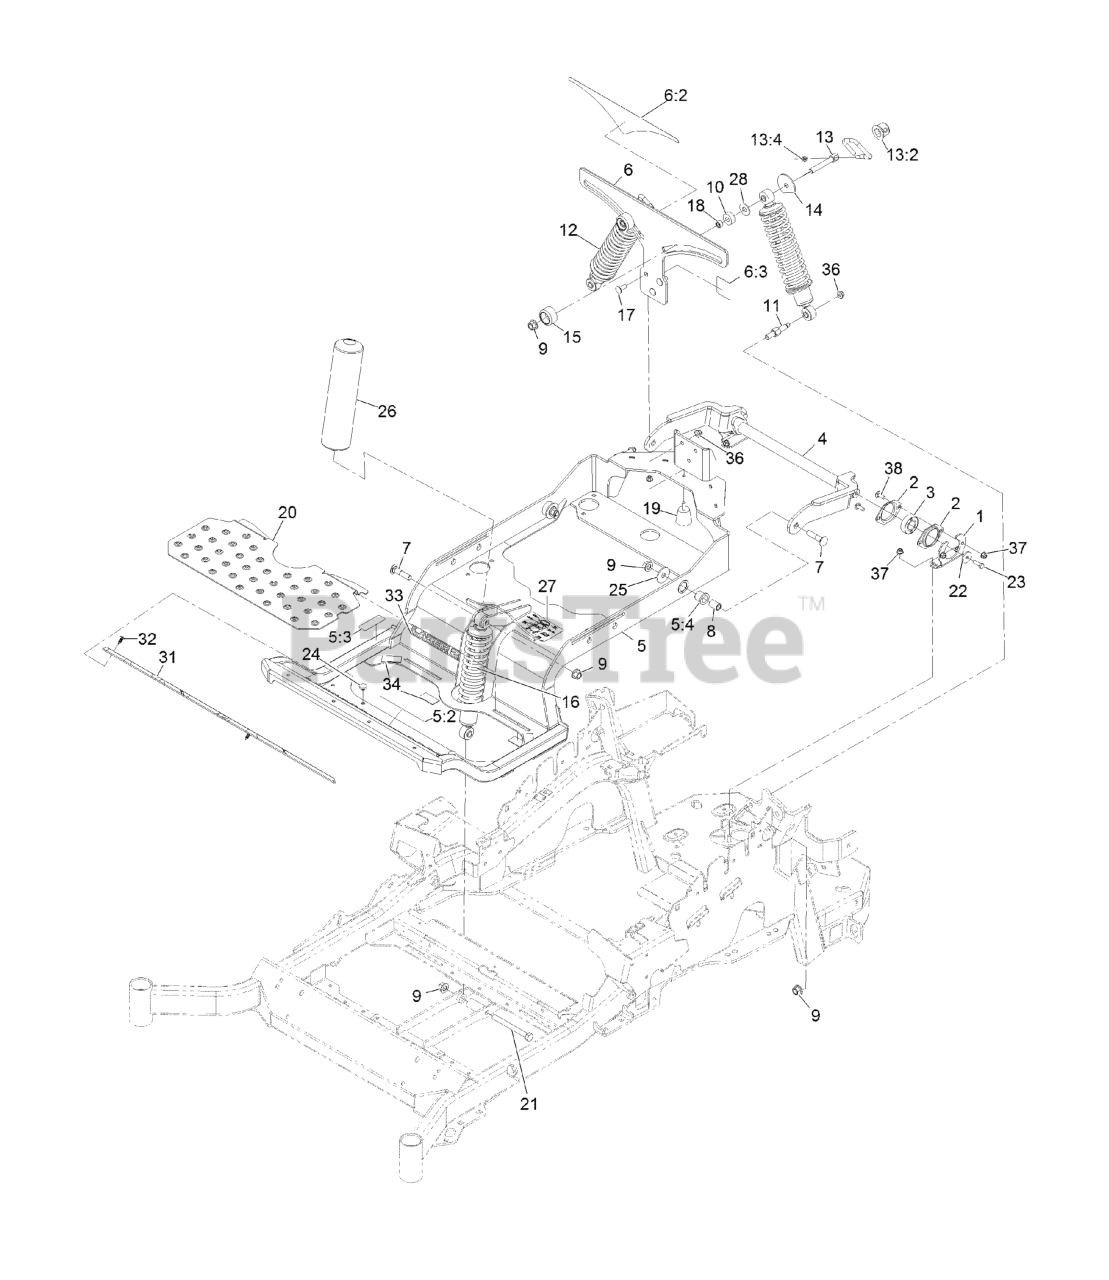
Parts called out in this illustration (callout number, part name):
1	BRACKET-BEARING
2	HOUSING-BEARING, FLANGE
3	BEARING
4	ARM-TRAILING
5	SUBFRAME ASM
5:2	DECAL-DANGER
5:3	DECAL-BRAKE, PARKING
5:4	BUSHING-FLANGE
6	BRACKET-MOUNTING
6:2	DECAL-ADJUSTMENT, RIDE
6:3	DECAL-LOCK, CAM
7	SCREW-CARR
8	SPACER-ALUMINUM
9	Nut-Lock 1/2-13
11	BOLT-SHOULDER
12	SHOCK/SPRING ASM
13	CAM LOCK ASM
13:2	CAP-LOCK
13:4	NUT-HEX
14	PLATE-STOP
15	KNOB-FRONT
16	SHOCK/SPRING ASM
17	SCREW-CARR
18	BEARING-NEEDLE
19	BUMPER-RUBBER
20	FLOORPAN
21	SCREW-HH
22	WASHER-FLAT
23	SCREW-HH, THREAD LOCKING
25	WASHER-THRUST
26	COVER-SHOCK
27	DECAL-SERVICE AID
28	WASHER-FLAT
31	FLOOR MAT
32	PLUG-PLASTIC
33	DECAL-LAZER LOGO
34	PAD-RUBBER
36	NUT-HF, NI
37	NUT-HF, NI
38	BOLT-CARR
